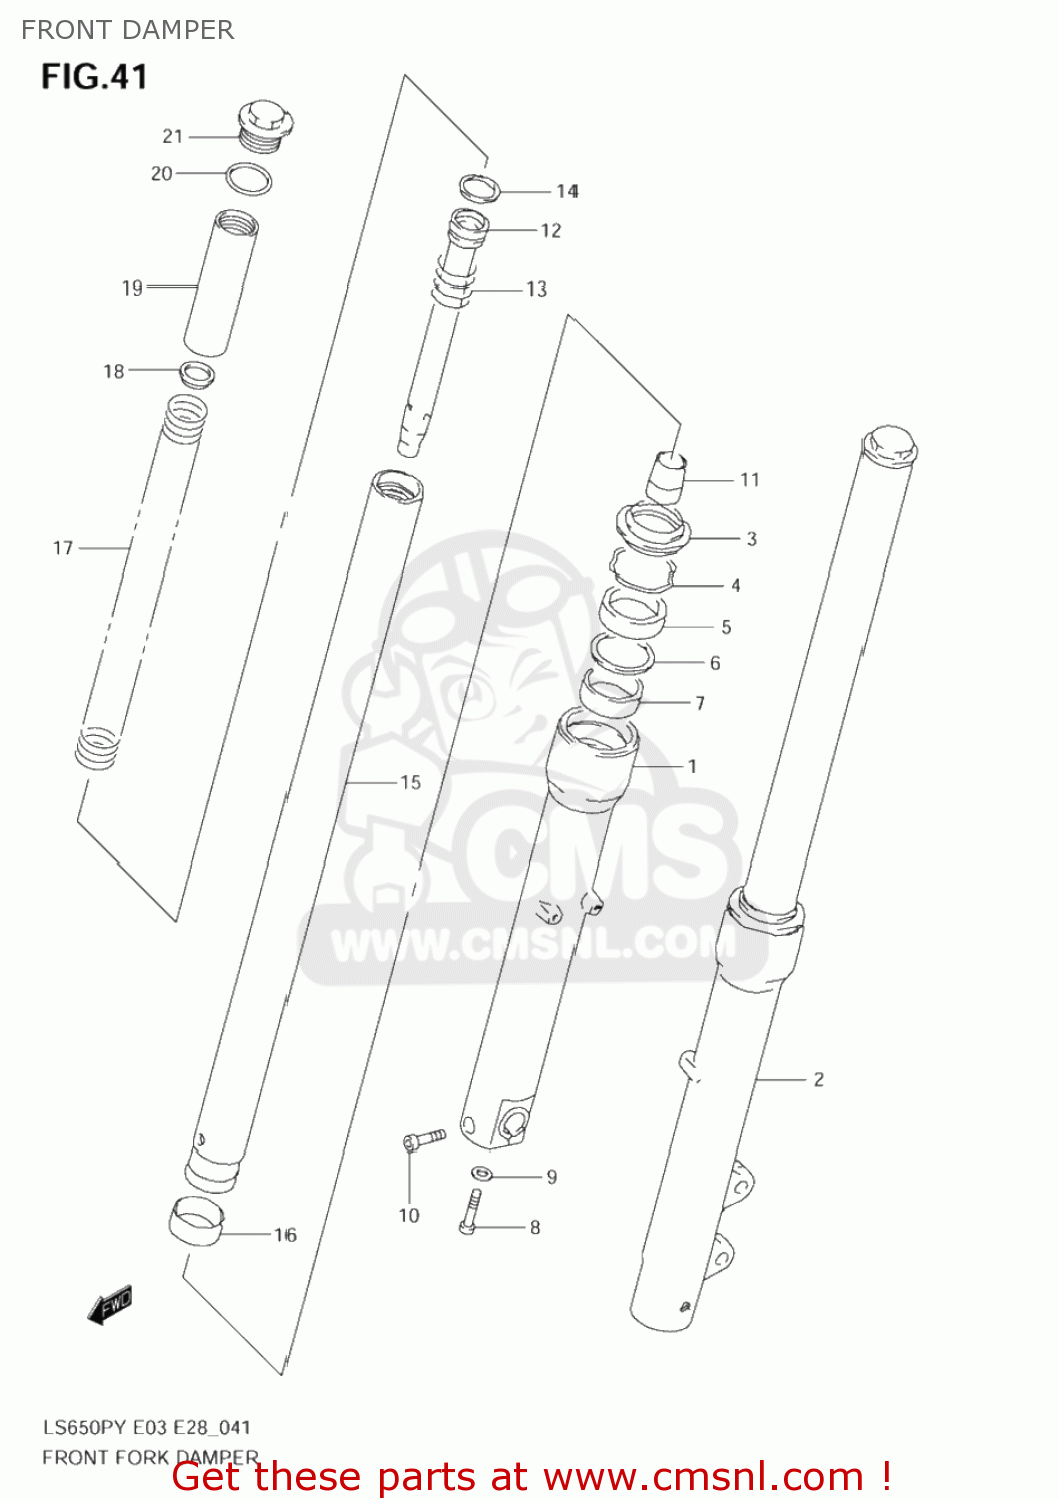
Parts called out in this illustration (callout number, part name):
1	TUBE,OUTER,R
2	TUBE,OUTER,L
3	SEAL,DUST
4	RING,STOPPER
5	SEAL,OIL
6	WASHER(40X50X2.3)
7	METAL,SLIDE
8	BOLT,FORK CYLINDER(10X25)
9	GASKET (NAS)
10	BOLT
11	PIECE,OIL LOCK
12	CYLINDER
13	SPRING,REBOUND
14	RING,PISTON
15	TUBE,INNER
16	PISTON
17	SPRING
18	WASHER
19	SPACER,SPRING
20	O RING
21	CAP
